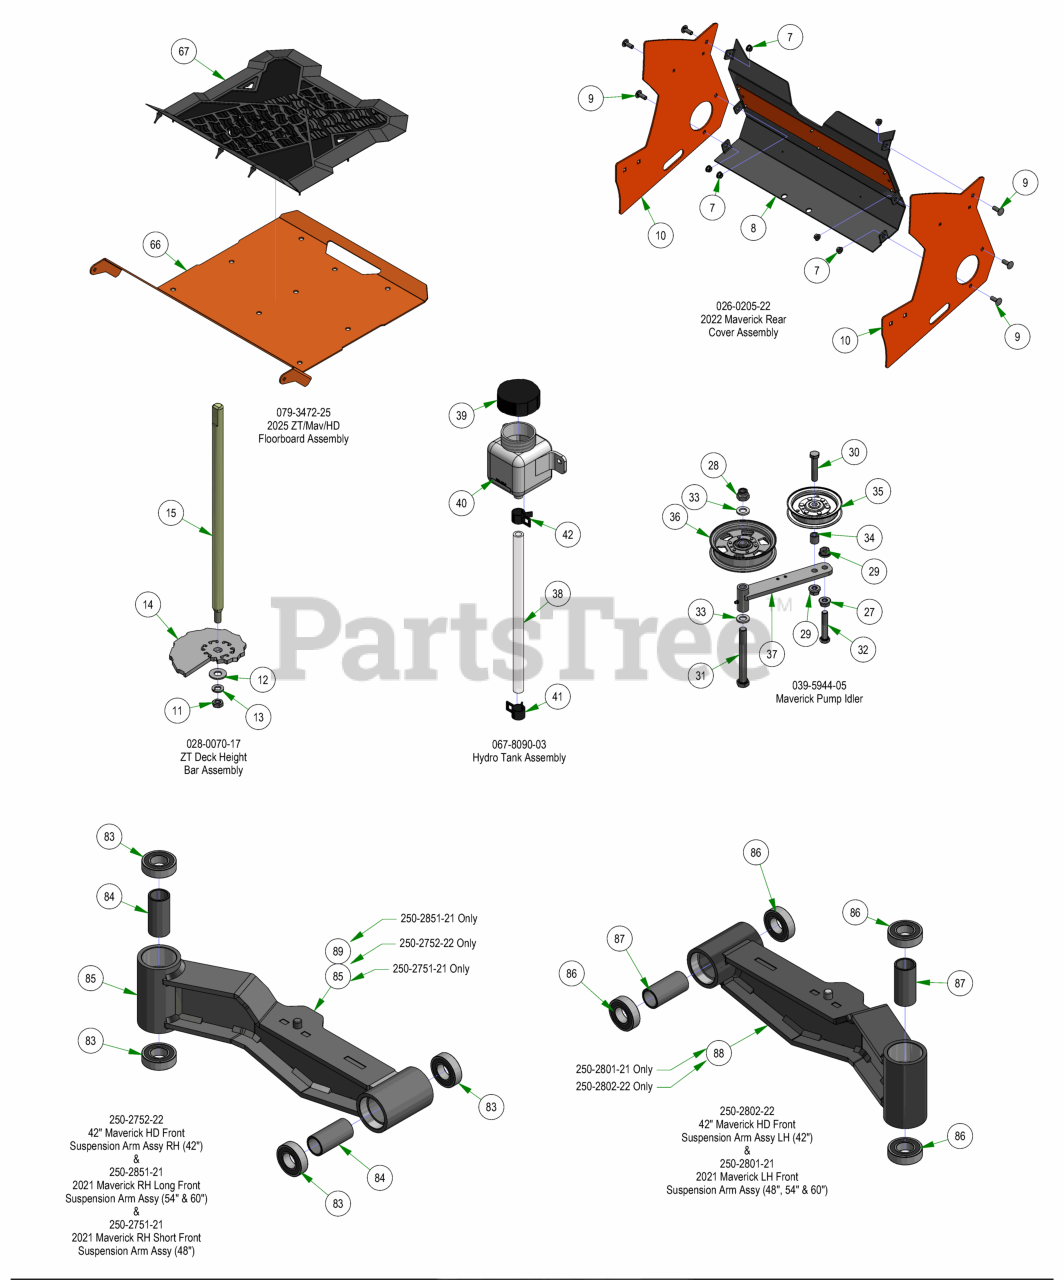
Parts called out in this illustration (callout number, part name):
1	Pillow Block MZ
2	Pillow Block Strap
3	5/16-18 NYLON INSERT FLANGE LOCKNUT ZINC
4	5/16-18 X 1 CARRIAGE BOLT (GR.8) ZINC
5	2017 MZ/ZT Shallow Foot Pedal
6	2017 MZ/ZT Deck Pedal Lever
7	5/16-18 NYLON INSERT FLANGE LOCKNUT ZINC
8	2021 Maverick Rear Cover Assembly
9	3/8-16 X 1 CARRIAGE BOLT (GR.5) ZINC
10	2022 Maverick Rear Cover Side Plate - Painted
11	3/8-24 HEX NUT ZINC YELLOW
12	3/8 FLAT WASHER USS (1" OD) ZINC
13	3/8 SPLIT LOCKWASHER ZINC
14	2017 MZ/ZT Cam Plate
15	2017 Deck Height Dial Rod ZT
16	3/8-16 Half Jam Nut
17	3/8-16 HEX SERRATED FLANGE NUT HARD/ZINC
18	3/8-16 X 2 HEX CAP SCREW (GR.5) ZINC
19	3/8 FLAT WASHER USS (1" OD) ZINC
20	Seat Spring
21	3/8-16 Half Jam Nut
22	3/8-16 HEX SERRATED FLANGE NUT HARD/ZINC
23	3/8-16 X 2 HEX CAP SCREW (GR.5) ZINC
24	3/8 FLAT WASHER USS (1" OD) ZINC
25	Seat Spring
26	Seat Strap with Buckles
27	1/2-13 HEX SERRATED FLANGE NUT HARD/ZINC
28	5/8-11 NYLON INSERT LOCKNUT ZINC
29	1/2-13 NYLON INSERT FLANGE LOCKNUT ZINC
30	1/2-13 X 2-1/2 HEX CAP SCREW GR 5 ZINC
31	5/8-11 X 5-1/2 HEX CAP SCREW (GR.5) ZINC
32	1/2-13 X 2-3/4 HEX CAP SCREW (GR.5) ZINC
33	.635 ID X 1.120 OD X .140 THICK FLAT WASHER NYLON
34	.51 ID X .75 OD X .75 LGTH SOLID SPACER ZINC
35	4 3/4" Idler Pulley
36	5 3/4 Idler Pulley, 5/8 Bore
37	Deck Idler
38	ZT/Maverick Hydro Tank Hose
39	Hydraulic Tank Cap
40	350ml Expansion Tank
41	3/8" Hose Clamp
42	1/2 Hose Clamp
43	3/8-16 HEX JAM 2-WAY REVERSIBLE CENTER LOCKNUT ZINC
44	5/16-18 NYLON INSERT CAP LOCKNUT ZINC (BLK CAP)
45	5/16-18 NYLON INSERT FLANGE LOCKNUT ZINC
46	5/16-18 HEX SERRATED FLANGE NUT HARD/ZINC
47	3/8-16 X 1-1/4 CARRIAGE BOLT ZINC
48	5/16-18 X 1 CARRIAGE BOLT (GR.8) ZINC
49	3/8 FLAT WASHER USS (1" OD) ZINC
50	2015 Brake Lever Spacer
51	.377 ID X .625 OD X .500 HGT X .880 FLNG DIA X .060 FLNG THK BUSHING
52	Brake Cable Extension Plate
53	Brake Load Balancer Lower Weldment
54	Load Balanced Brake Handle with Grip
55	Set of Armrests-SS Front Adj
56	RH Armrest-Selfskin Front Adj
57	LH Armrest-Selfskin Front Adj
58	Weight Adjust Indicator Knob Assy
59	4" Single Locking Track Kit
60	Delta Plunger Switch - N.O.
61	Recliner Adjustment Knob-New
62	Bellows w/Hardware
63	2" Retractable Belt Kit w/Spacers
64	Back Cover, 2025 Suspension Seat
65	Cushion Cover, 2025 Suspension Seat
66	2025 Elite Maverick Floorboard
67	25 Mav Floor Mat. V4
68	10-24 Nylon Insert Locknut Zinc Orange Nylon
69	Light Plug
70	10-24 X 5/8 BS Button Head Bolt
71	Throttle Lever Assembly
72	PTO Engager
73	Ignition Switch
74	2022 Maverick HD control panel
75	Tachometer
76	2023 MZ/Magnum/ZT/Maverick Control Panel Decal
77	Tachometer
78	4-Way Key Switch
79	Relay Block Cover Replacement Kit
81	Relay Block Cover Replacement Kit
83	1641 BEARING W/2 CONTACT RUBBER SEALS
84	2016 Front Bearing Spacer
85	2021 Maverick I-Beam Front Arm RH Short Weldment - Painted
86	1641 BEARING W/2 CONTACT RUBBER SEALS
87	2016 Front Bearing Spacer
88	2021 Maverick I-Beam Front Arm LH Weldment - Painted
89	2021 Maverick I-Beam Front Arm RH Long Weldment - Painted
90	2022 Maverick RH Front Suspension Arm Assy (42'')
91	2022 Maverick LH Front Suspension Arm Assy (42'')
